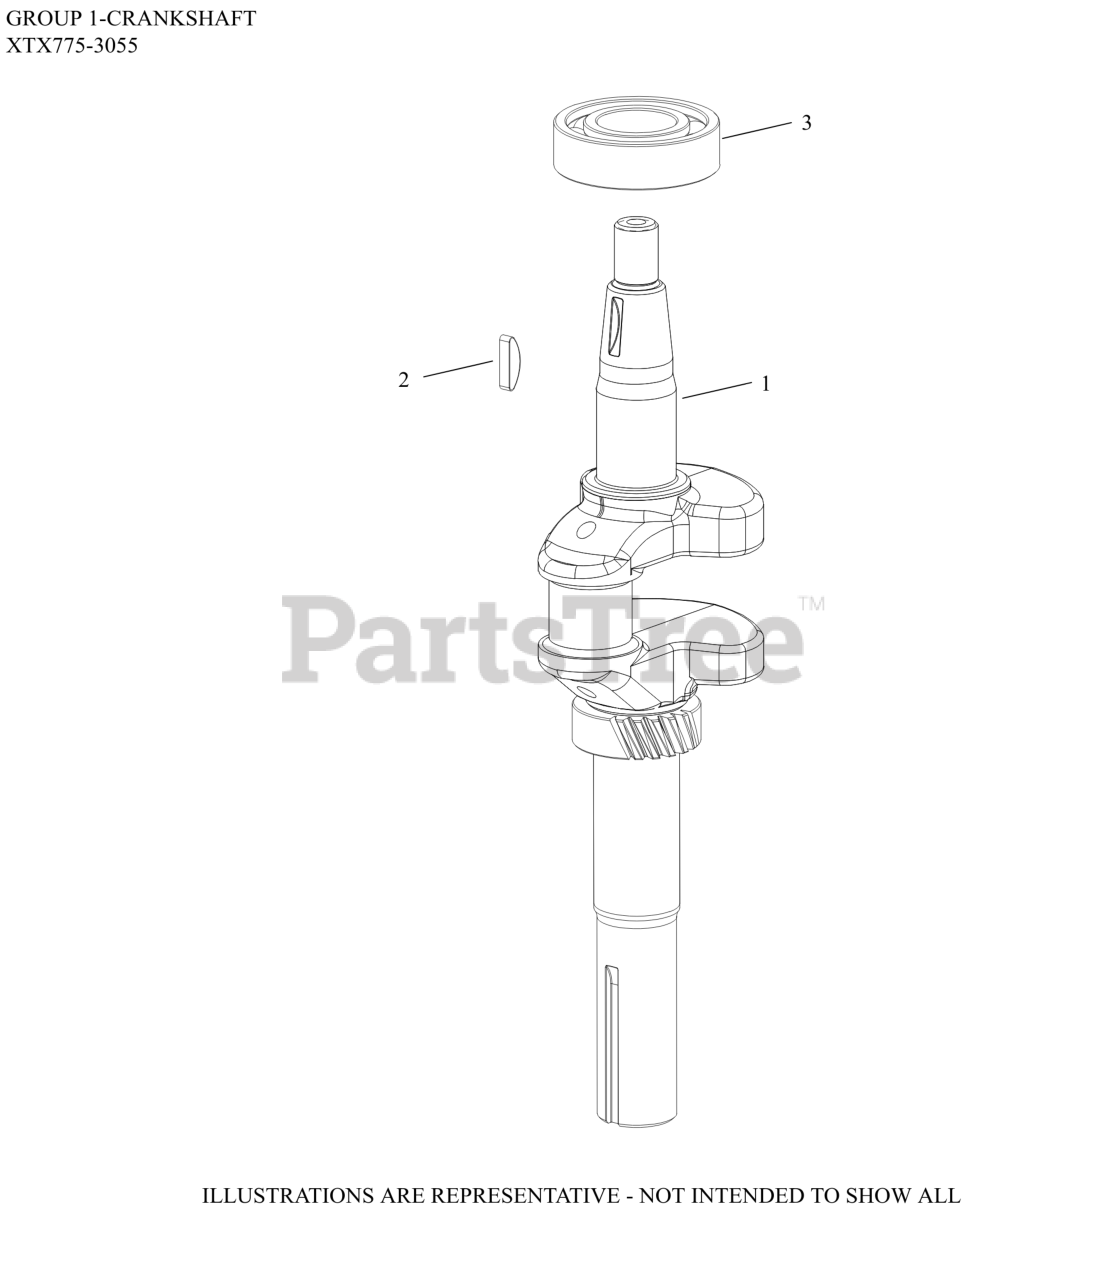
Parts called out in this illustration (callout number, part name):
1	CRANKSHAFT ASSEMBLY
2	KEY, FLYWHEEL
3	BEARING, BALL
